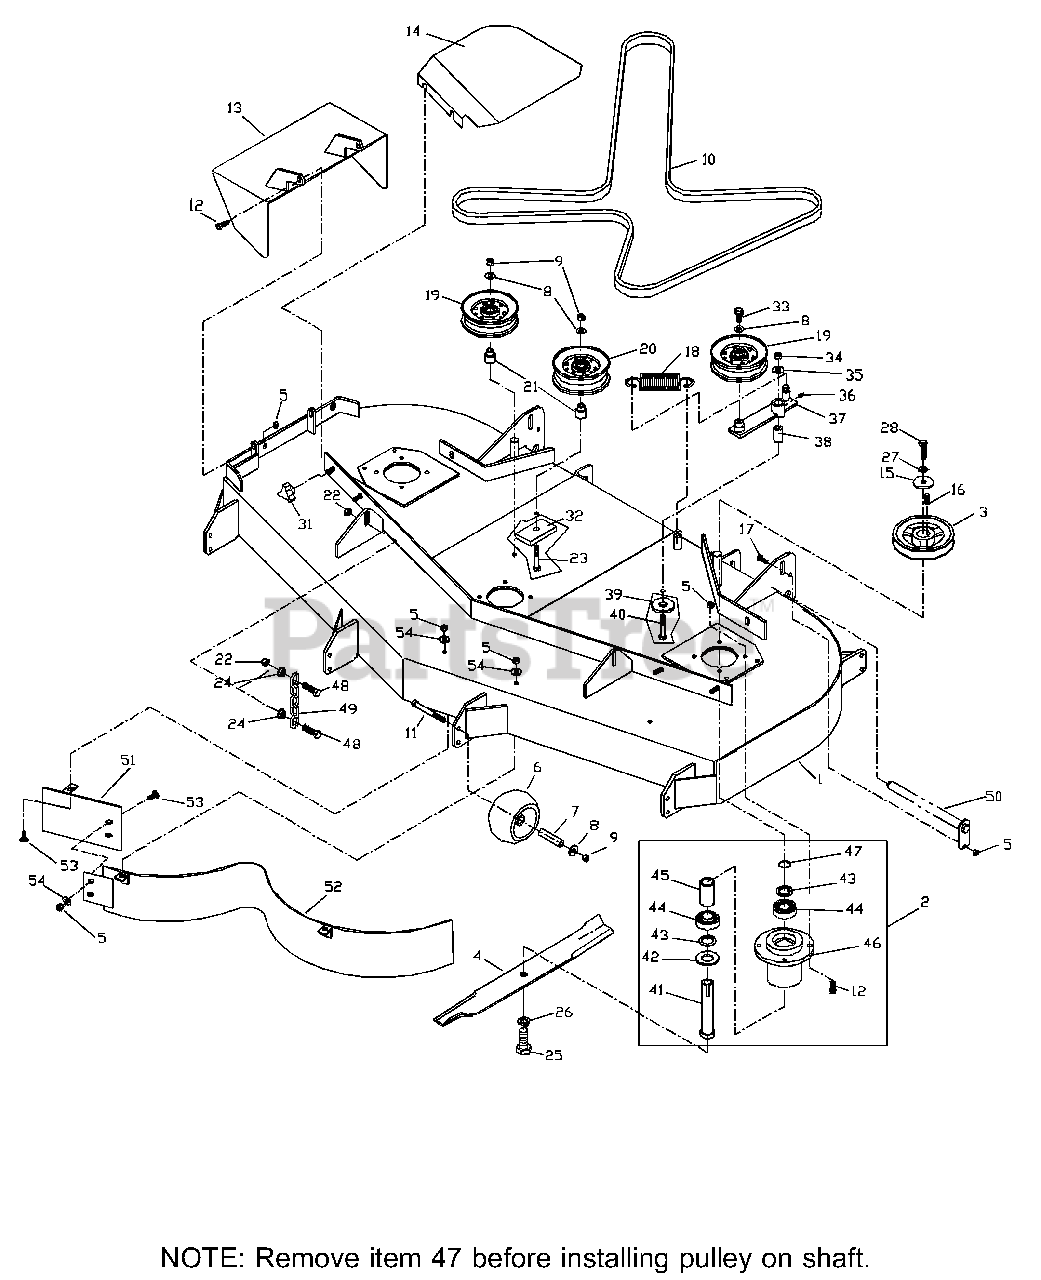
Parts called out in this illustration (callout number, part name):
1	DECK W/DECALS
2	CUTTER HOUSING ASM.
5	NUT 5/16 LOCK
8	3/8 FLAT WASHER
9	NUT 3/8 LOCK
10	BELT
11	HCS 3/8 X 3.5
12	HCS 5/16 X 1.00
13	DISCHARGE CHUTE
14	BELT SHIELD RT.
14	BELT SHIELD LT.
16	KEY 1/4 SQ.
17	HCS 5/16 X .750
19	PULLEY 1.31
20	PULLEY 1.62
21	IDLER BUSHING
22	NUT 7/16 LOCK
23	HCS 3/8 X 2.5
24	NUT 7/16 WHIZ
25	HCS 5/8F X 1.25
26	WASHER 5/8 LOCK
27	7/16 LOCK WASHER
28	HCS 7/16F X 1.5
32	PAD
33	HCS 3/8 X 1.0 SERR.
34	NUT 1/2 NYLOC
35	WASHER 1/2 FLAT
36	ZERK
38	PIVOT BUSHING
39	SUPPORT WASHER
40	HCS 1/2 X 3.25
42	MACHINE BUSHING
43	MACHINE BUSHING
44	BEARING
48	HCS 7/16 X 1.5
49	LIFT CHAIN
51	BAFFLE , CENTER
52	BAFFLE, MAIN
53	RHSNB 5/16 X 5/8
54	5/16 FLAT WASHER
